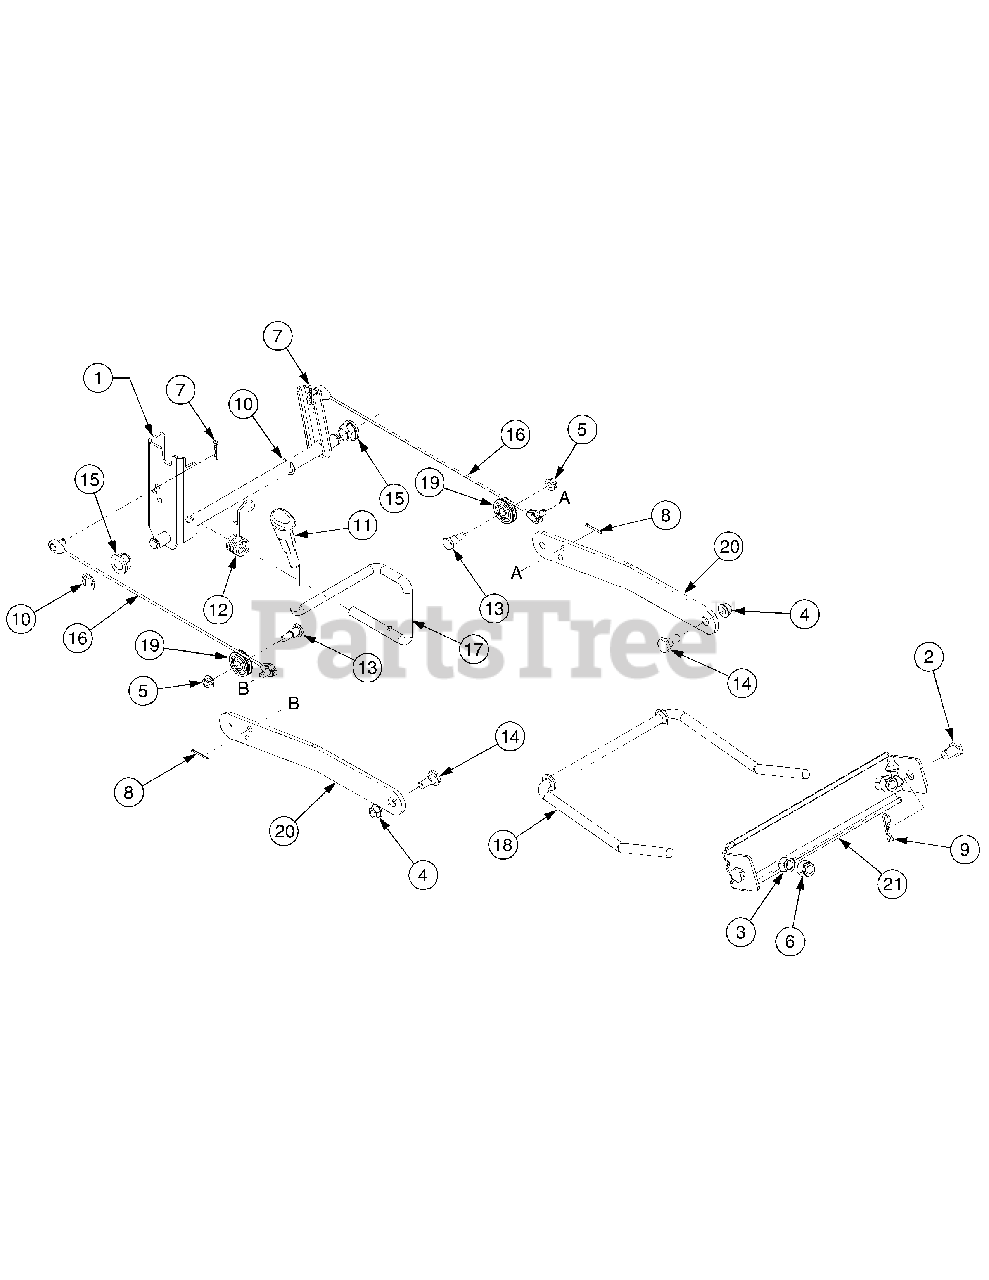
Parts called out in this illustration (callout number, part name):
3	Nut, Hex, 1/2-13, Gr5
4	Nut, Flange Insert Lock, 3/8-16 GrF
5	Nut, Flange Insert Lock, 5/16-18, GrF
6	Nut, Hex Lock, 1/2-13, Gr8, Nylon
7	Pin, Cotter, .072 Dia. x 1.13 Lg
8	Pin, Cotter, 3/32, 1.0
9	Pin, Internal Cotter, .080 x 1.56 Lg
10	E-ring, .625 Dia. Shaft
11	Grip, Handle
12	Spring, Torsion
13	Screw, Hex Cap, 5/16-18x.620 Gr2
14	Shoulder Screw, .5 x .27:3/8-16
15	Bearing, Hex Flange
16	Cable, Lift, 16.16 Lg
17	Handle, Lift
18	Rod, Deck, Front Adjustment .5" Dia
19	Pulley, Roller
